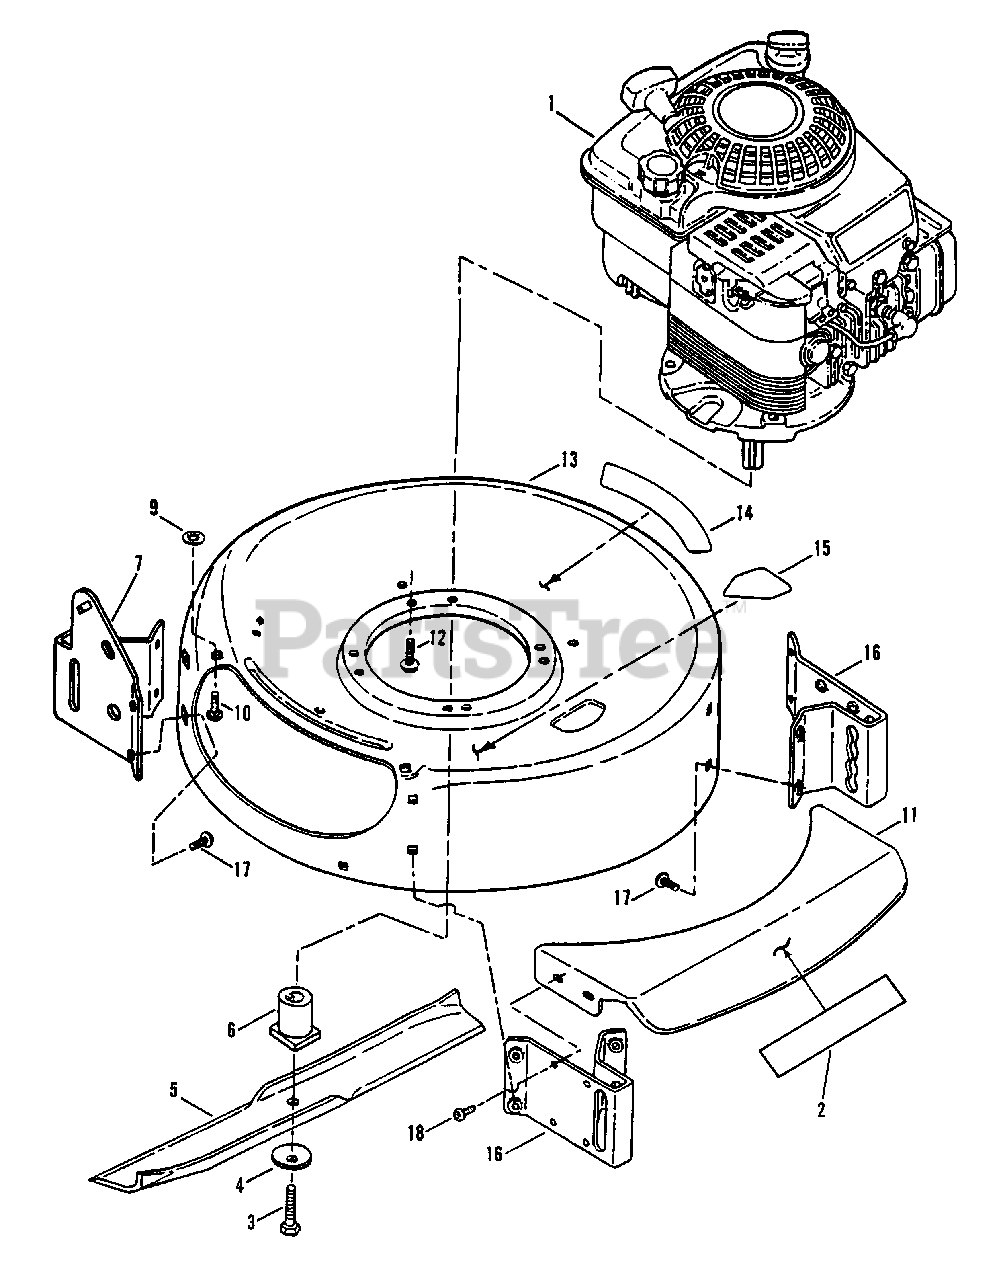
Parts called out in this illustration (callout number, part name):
1	*ENGINE, 5 HP Briggs & Stratton XM
2	DECAL, Front
3	SCREW, 3/8-24 x 2 Hex Head Cap, Grade 5
4	WASHER, Cone
5	BLADE, Mulching
6	HUB, Blade
7	BRACKET, Rear Wheel
9	RETAINER, 5/18 Bolt
10	BOLT, 5/16-18 x 3/4" Short Neck Carriage, Grade 5
11	PLATE, Deck Front
12	SCREW, 3/8-16 x 2 Hex Washer Head, Self-Tapping
13	DECK, 20" Cutting
14	DECAL - WARNING
15	DECAL - DANGER
16	BRACKET, Front Wheels
17	SCREW, 5/16-18 x 1/2" Pan Head Torx, Self-Tapping
18	SCREW, #10-24 x 1/2" Hex Washer Self-Tap (Torx)
